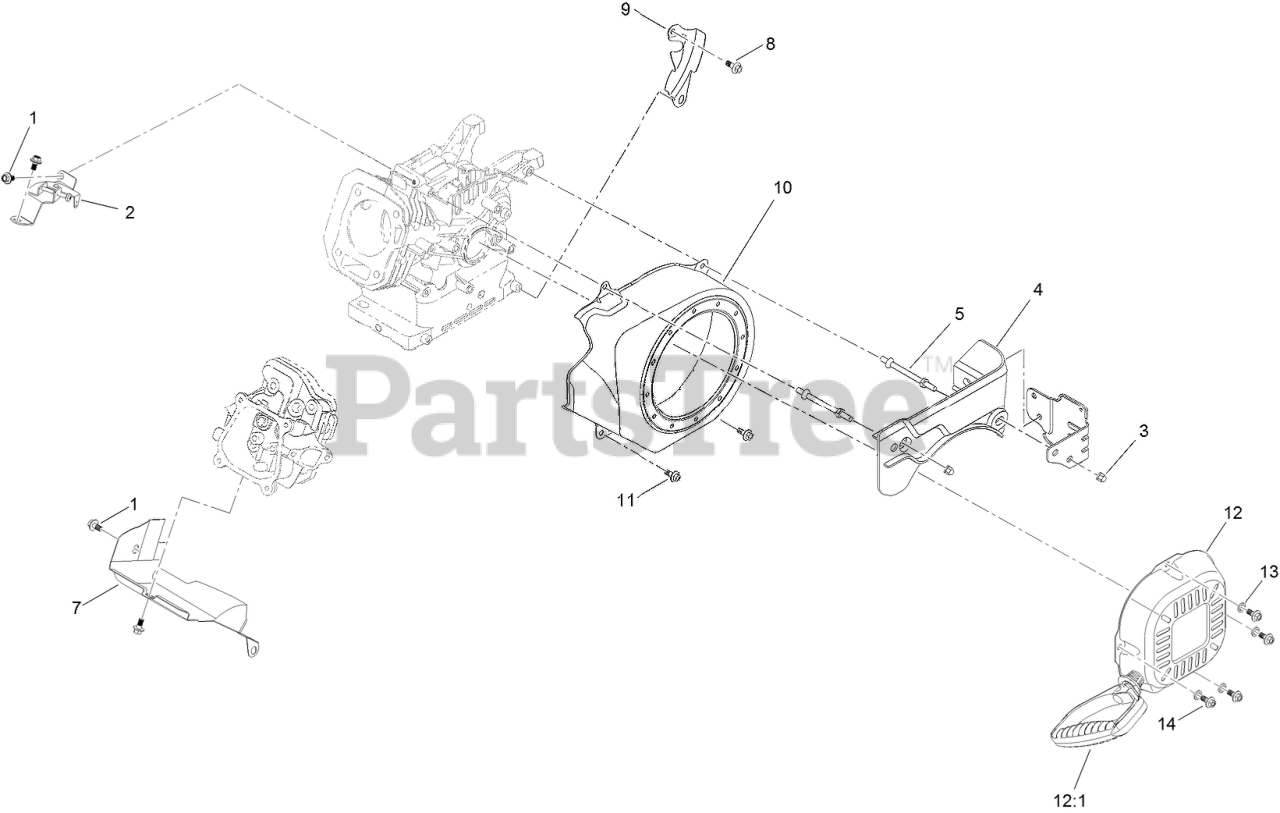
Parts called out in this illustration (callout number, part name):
1	SCREW-HHF
2	SPEED CONTROL ASM
3	NUT-ACORN
4	PANEL-FRONT
5	STUD-MOUNT
7	SHROUD-LOWER
8	SCREW-HHF
9	SHIELD-FLYWHEEL
10	SHROUD-BLOWER
11	SCREW-HHF
12	RECOIL STARTER ASM
12:1	HANDLE-RECOIL
13	WASHER-PLAIN
14	SCREW-HHF
